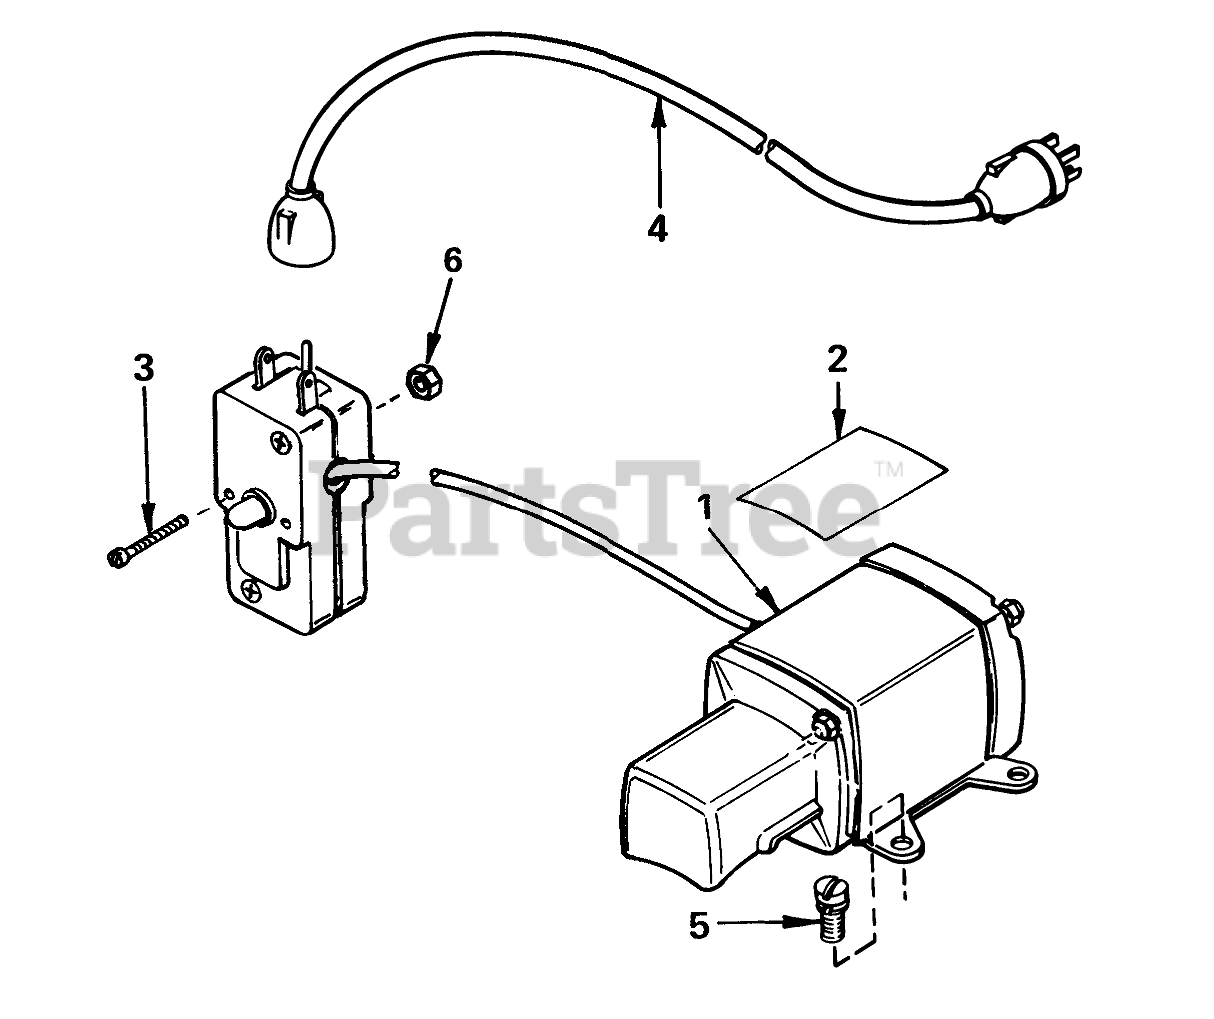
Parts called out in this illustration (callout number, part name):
1	Motor, Cranking (CSA Approved) (Incl. #2 thru 6)
2	Decal
3	Screw, Pan Hd.
4	Cord-Extension
5	Screw (T-30, 1/4-20 x 23/32)
6	Nut & Lockwasher
